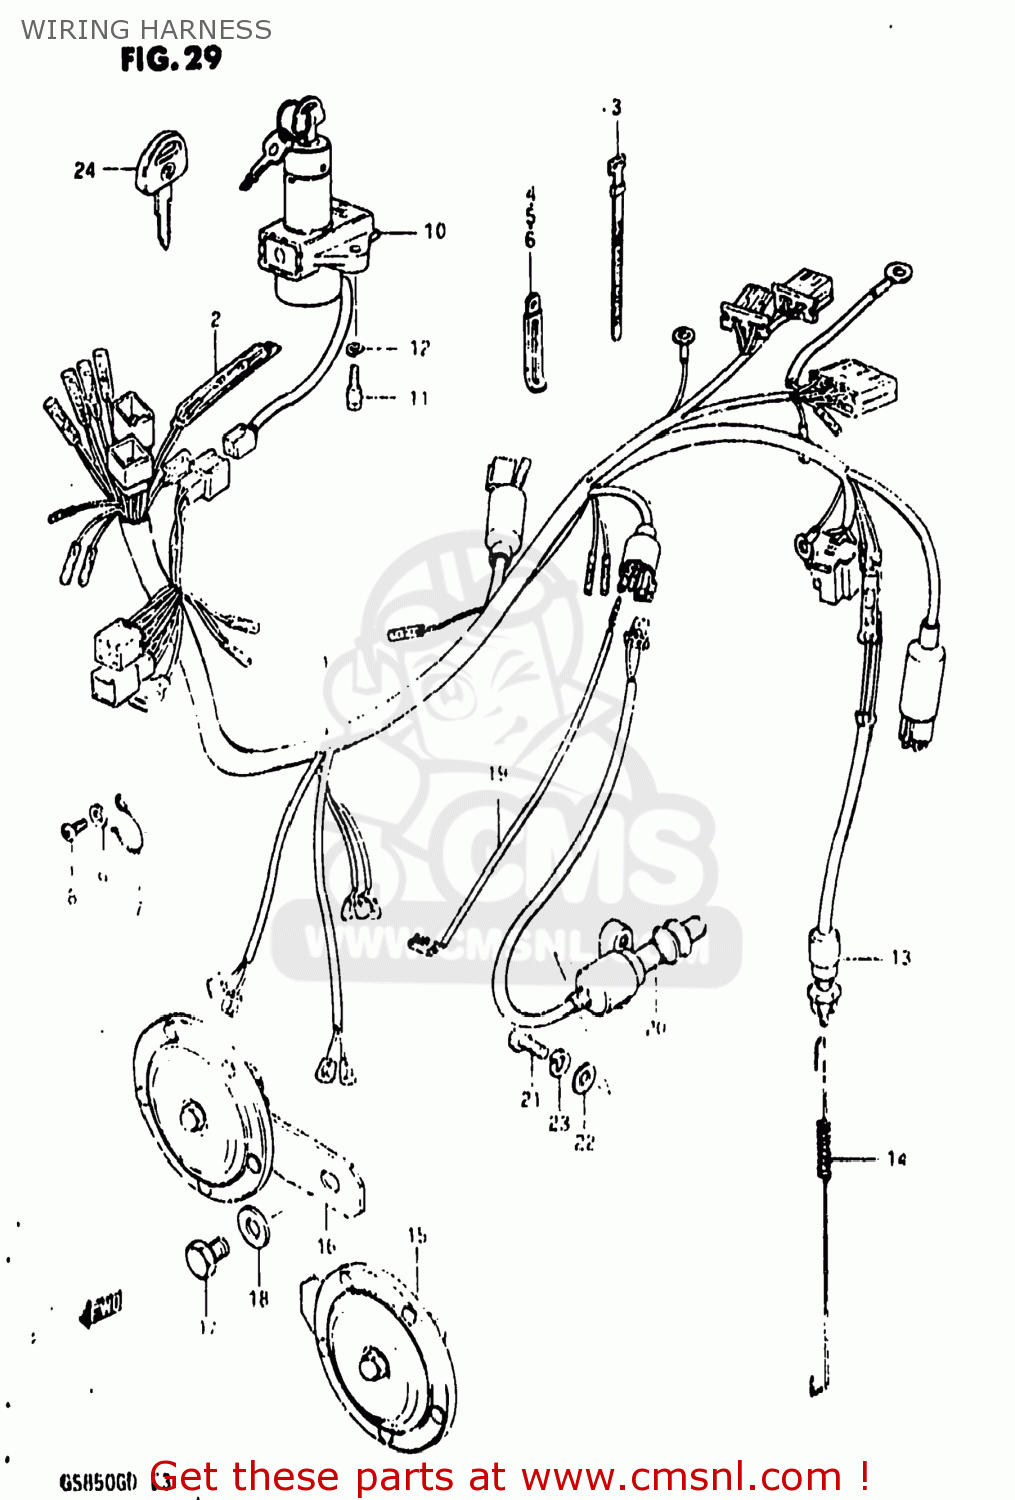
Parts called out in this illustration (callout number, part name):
1	HARNESS,WIRING
2	DIODE
3	CLAMP(L:120)
4	CLAMP
5	CLAMP
6	CLAMP
7	GUIDE,WIRING HARNESS
8	SCREW 6X12
9	WASHER
10	SWITCH ASSY,IGNITION
11	BOLT
12	LOCK WASHER
13	SWITCH ASSEMBLY,STOP LAMP
14	SPRING
15	HORN ASSEMBLY,LOW PITCH
16	HORN ASSEMBLY,HIGH PITCH
17	BOLT
18	WASHER
19	WIRE
20	SWITCH ASSEMBLY,SIDE STAND
21	BOLT
22	WASHER
23	LOCK WASHER
24	KEY,BLANK
